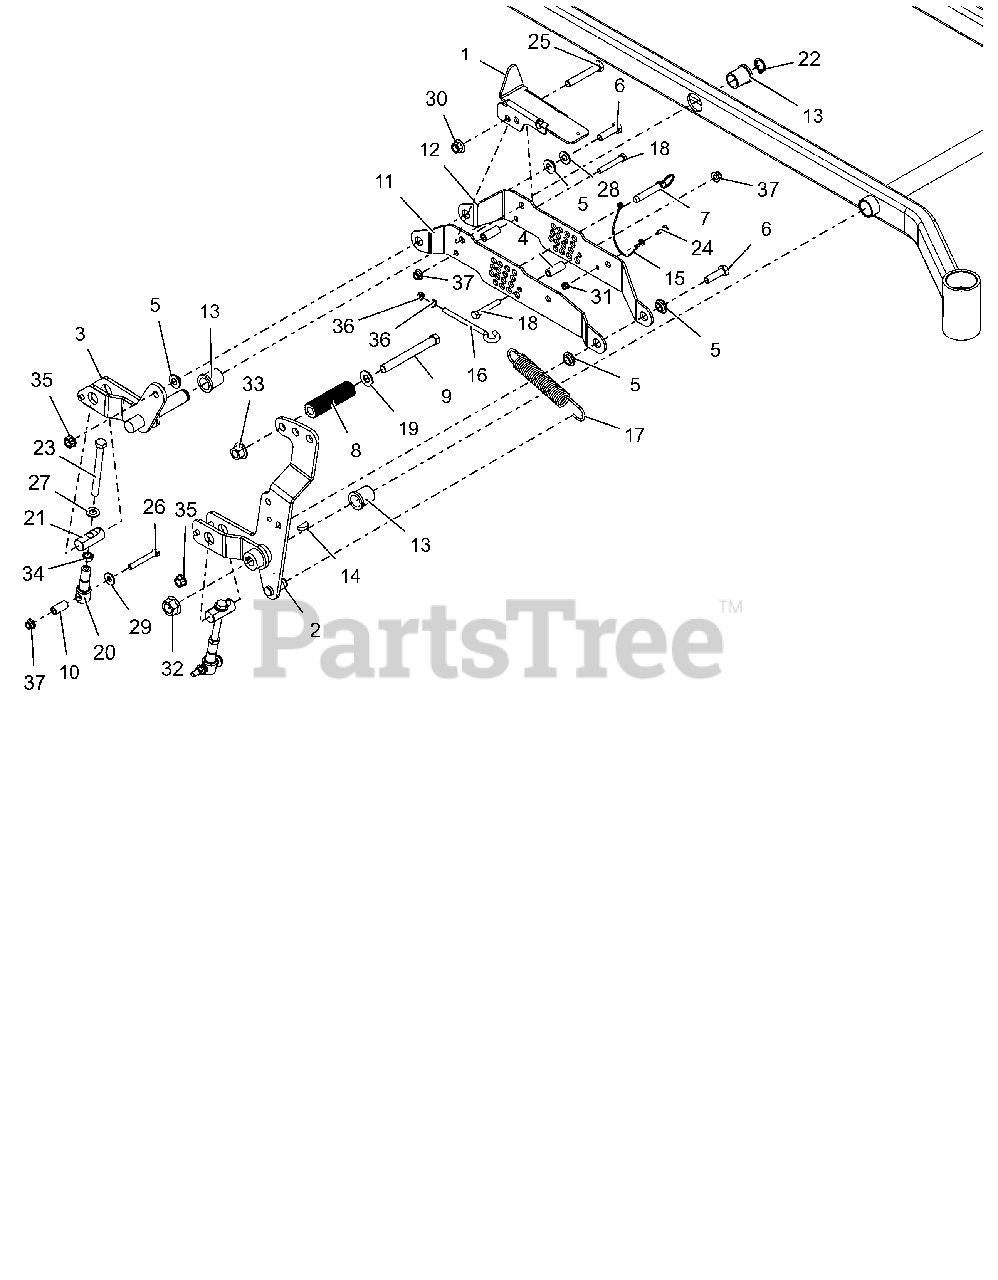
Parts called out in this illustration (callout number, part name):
1	MECHANICAL LOCK-UP WMT - BLACK
2	FRT RH DECK LIFT ARM WMT- LF
3	REAR RH DECK LIFT ARM WMT- LF
4	SPACER, .375 X .625 X 1.54
5	BSHG-FLG .515X.750X.310X1.120
6	@BLT-HEX .50-13X1.75 GR5 YWZC
7	PIN, .50 X 2.00 USABLE LG BALL
8	ROD, FOOT PEDAL (BLACK)
9	BLT, HEX .62-11X5.50 G5 FBP
10	SPACER, DECK LEVELING
11	RH OTBRRD LIFT/CUT HT BRKT-BLK
12	RH INBRD LIFT/CUT HT BRKT-BLK
13	BSHG-FLG 1.00X1.25X1.50X1.50
14	KEY-WDRF .25X1.00 HRD #15
15	CABLE, 12.0 LANYARD, NYLON
16	BOLT,.38-16 X 4.25-.62 DIA EYE
17	SG-TENS .162X1.25X8.25 WLD 25
18	@BLT-HEX .38-16X2.50 GR5 YWZC
19	WSHRFLT 5/8SAE CARBHARD FBP
20	LINK, DECK LIFT FORMED
21	PIN, DECK LIFT
22	RG-RTNG-EXT 1.00X.078
23	BOLT, 1/2-13 X 5.0 2.5 THREAD
24	@BLT-HEX .25-20X.75 GR5 YWZC
25	@BLT-HEX .50-13X3.25 GR5 YWZC
26	BLT-HEX .38-16X2.75 GR8 YWZC
27	FLATWASHER 1/2 SAE HARD 15906
28	WSHR,FLT .531X1.062X.095 ZCC
29	@WSHR-FL-STL.438X1.00X.083 YWZ
30	@NUT-LK-NYL-FLG .50-13 YWZC
31	@NUT-LK-NYL-FLG .25-20 YWZC
32	NUT-HEX-FLG-TPLK .75-10 YWZC
33	NUT,FLG-TOP LK .625-11 FBP
34	NUT-JAM .50-13 YWZC
35	NUT-LK-CTR-FLG .50-13 YWZC
36	NUT-HEX-JAM .375-16 YWZC
37	@NUT-LK-NYL-FLG .38-16 YWZC
